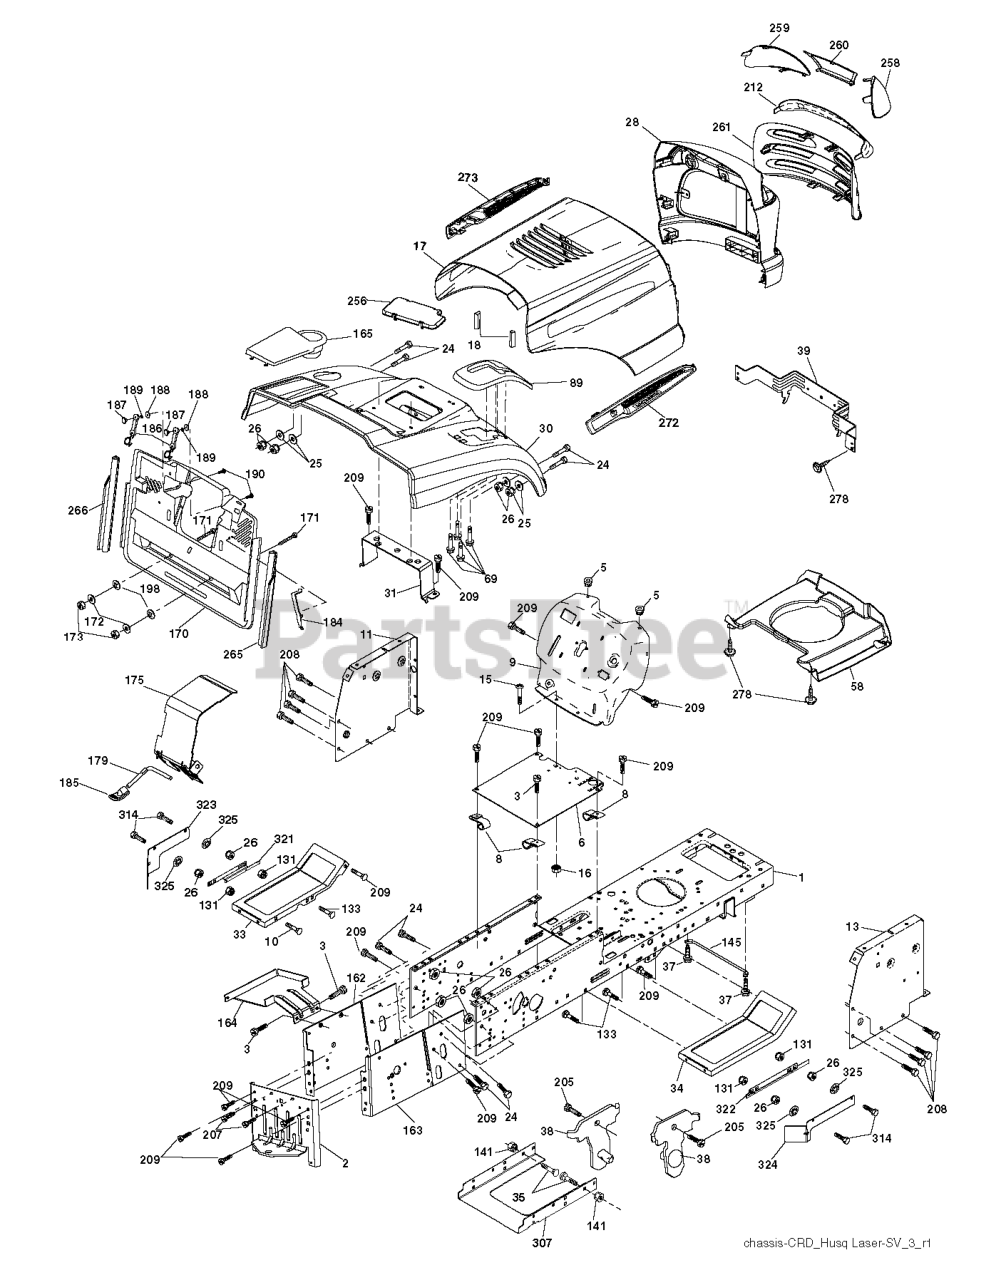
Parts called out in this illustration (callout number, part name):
2	DRAWBAR
3	SCREW 3/8-16X3/4
5	BUMPER.RUBBER.HOOD
6	PLATE
8	CLIP,INSULATOR
9	DASH.SLKSCR.PLM
10	BOLT.3/8-14X1.25
11	PANEL.DASH.LH.LTX
13	PANEL ASM, DASH RH
15	Screw, Machine, Truss Head 5/16-18 UNC x 3/4
16	NUT
17	HOOD.PNT.LASER.SV.LT.668
18	BUMPER.HOOD.LARGE.1.75"
24	BOLT
25	WASHER
26	NUT
28	GRILLE.HUSQ.LASER.LT.668
30	FENDER.PNT.CRD.MS-668
31	BRACKET SUPPORT FENDER
33	FOOTREST.PNT.LH.GREY
34	FOOTREST.PNT.RH.GREY
35	BOLT
37	Screw 5/16-18 x 1/2 Hex, Self Tapping 5/16-18 x 1/2
38	BRACKET ASM PIVOT MOWER REAR
39	BRACKET PIVOT
69	SCREW.HI-LO.CONSOLE
89	CONSOLE.CRD.AUTO.GRY
131	NUT.HEX.3/8-16UNC
133	BOLT D
141	NUT LOCK FLG 3/8-16 UNC
145	ROD.PIVOT.HOOD
162	BRACKET
163	BRACKET EXTEN CHASSIS RH CRD
165	COVER.BATT.CUPHOLDER.CRD
171	BOLT
172	WASHER
175	DOOR TRAP
179	ROD PIVOT FBI
184	BRACKET.ACTUATOR.BAGGER.SRD
185	KNOB.BRAKE.PARKING.ROD
186	LATCH ASSY
187	WELDNUT
189	LOCKWASHER #10
190	SCREW
205	SCREW LT
207	SCREW, 5/16-18 X 1/2
208	SCREW 3/8-16X1/2
209	SCREW, 3/8-16X3/4
212	INSERT.LENS.REFLECTIVE
256	COVER FENDER CRD
258	LENS LH
259	LENS LH
260	COVER.LENS.HUSQ.LASER.LT.498
261	INSERT.GRILLE.HUSQLASER.LT.498
265	SEALING
266	SEALING
272	VENT.HOOD.LASER.III.SD.RH
278	SCREW.#10 X 0.750.BOS
307	GUARD 107 CRD FRENCH GUARD HYD
314	SCREW 1/4X20
321	SHIELD INNER LEFT
322	SHIELD INNER RIGHT
323	PLATE LEFT
324	PLATE RIGHT
325	PALNUT 1/4
